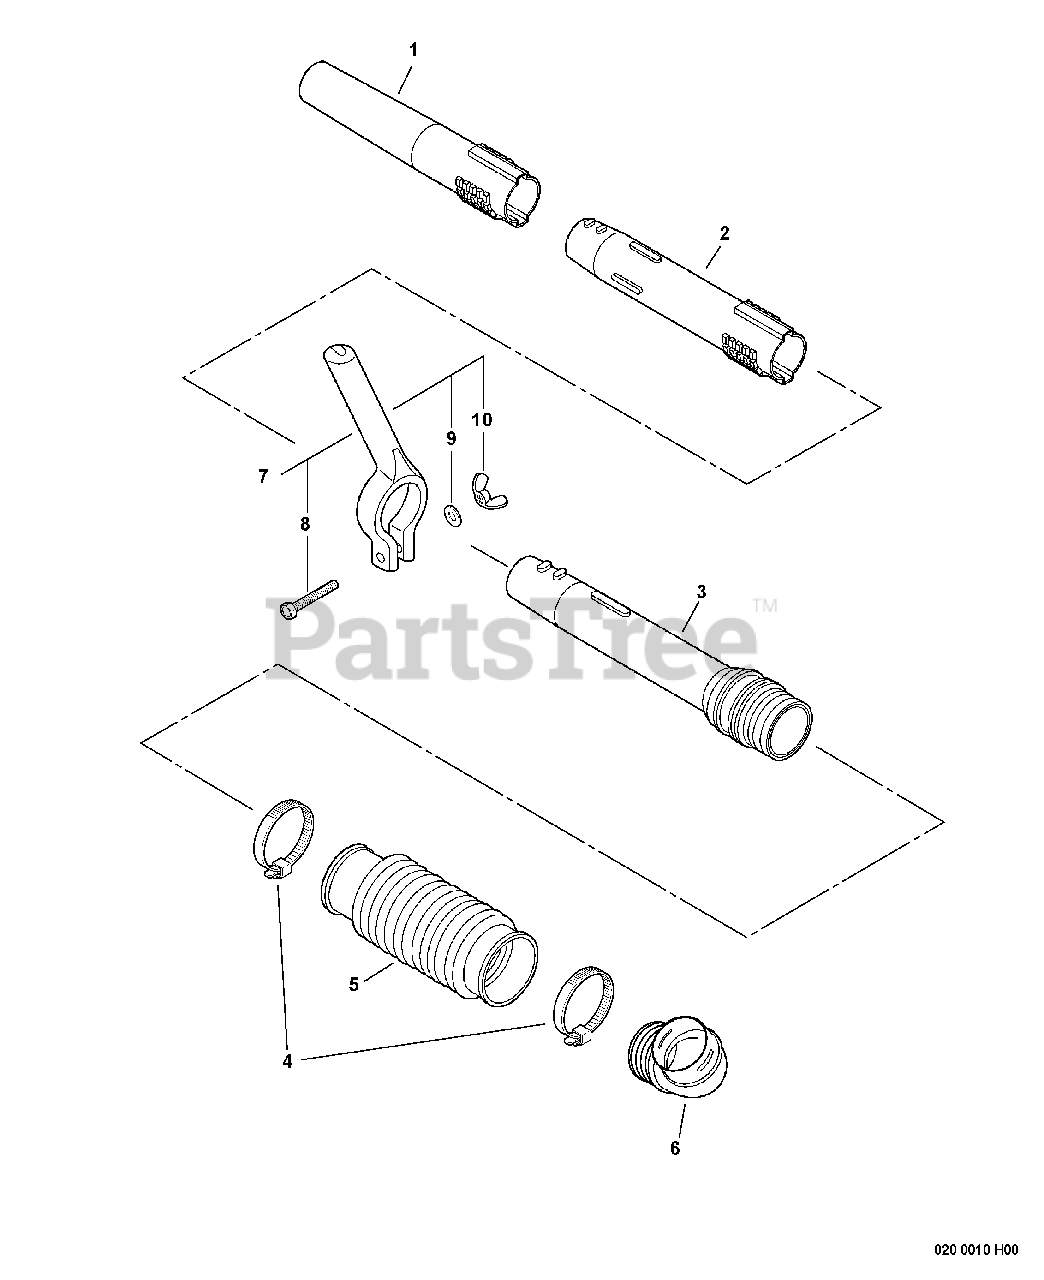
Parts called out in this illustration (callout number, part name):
1	TUBE, BLOWER - ROUND NOZZLE
2	TUBE, BLOWER - STRAIGHT
3	TUBE, BLOWER - SWIVEL
4	CLAMP 58.7 MM / 82.5 MM
5	TUBE, BLOWER - FLEXIBLE
6	TUBE, BLOWER - ELBOW
7	HANDLE ASSY, PB LARGE
8	BOLT 6×45
9	WASHER 6.5×11.5×0.8
10	NUT, WING 6
